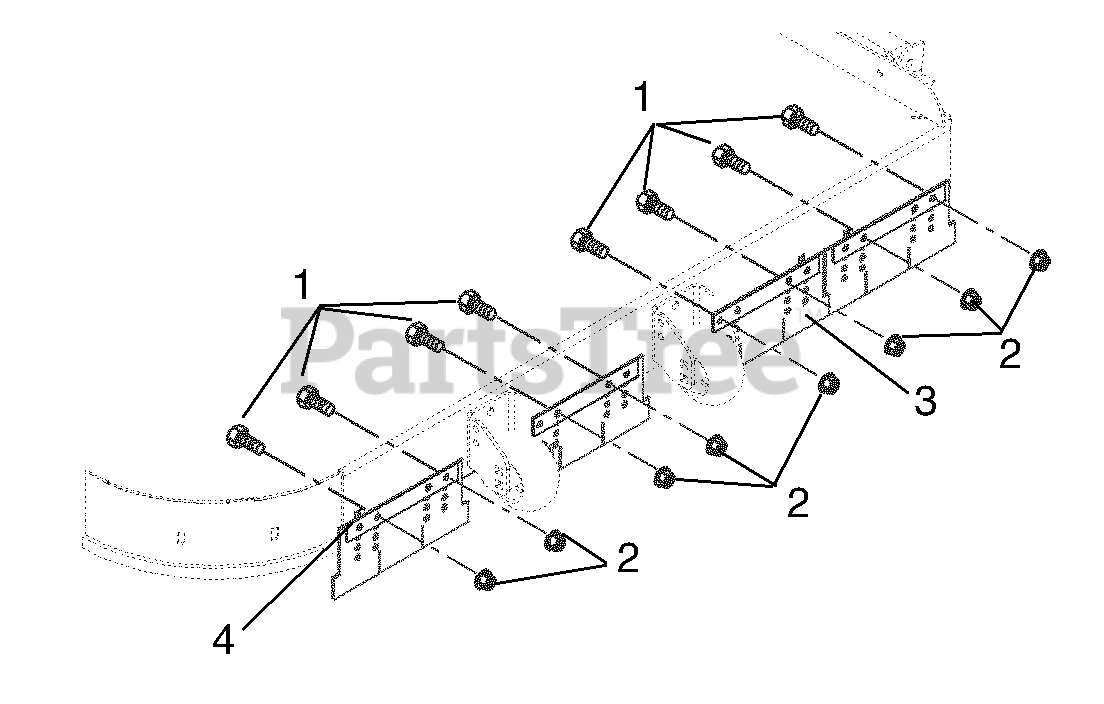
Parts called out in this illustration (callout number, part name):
1	@BLT-HEX .38-16X1.00 GR5 YWZC
2	@NUT-LK-TOP-FLG .38-16 YWZC
3	SKIRT, RUBBER STRIPER
4	BAR, STRIPER
